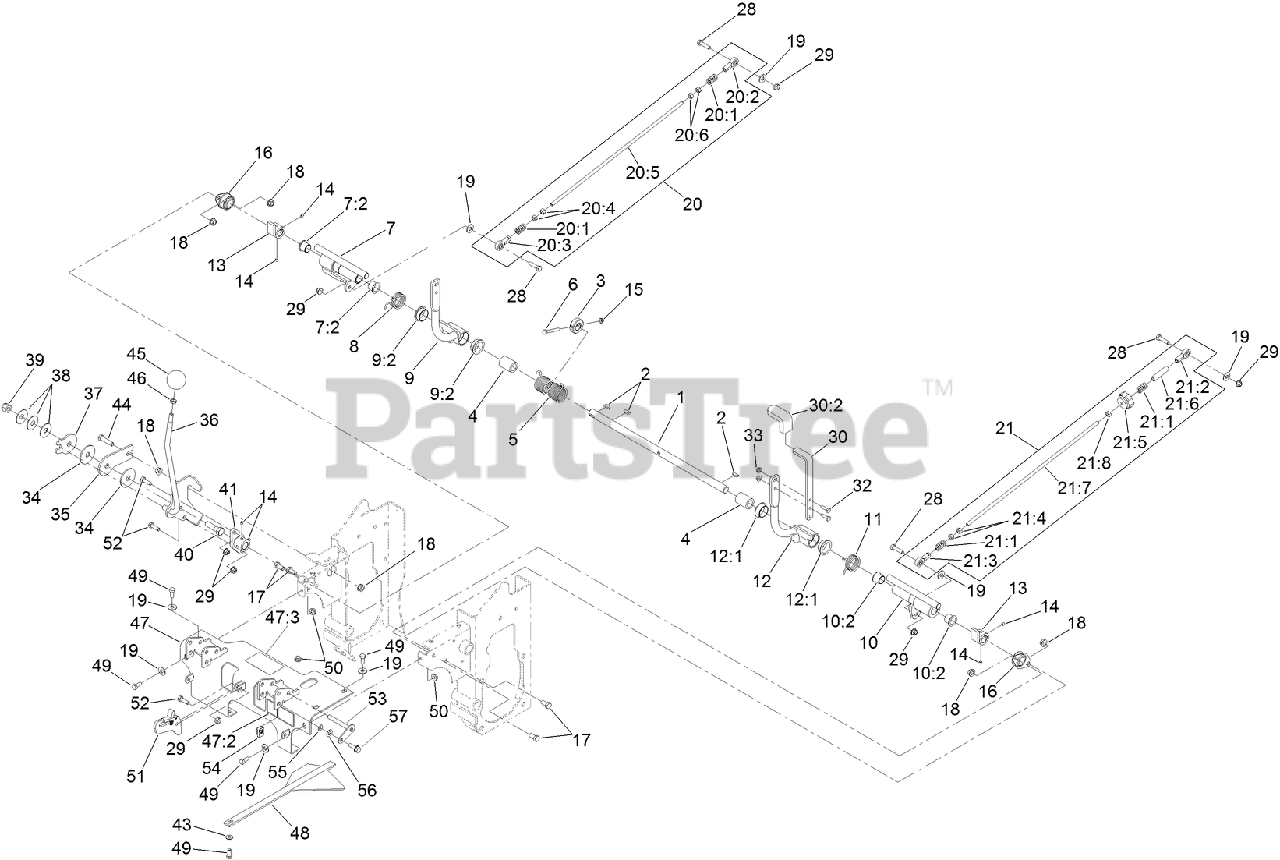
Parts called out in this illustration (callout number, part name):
1	SHAFT-CONTROL, SPEED
2	KEY-WOODRUFF
3	STOP-HUB, CENTER
4	BUSHING-PLASTIC
5	SPRING-TORSION, DOUBLE
6	SCREW-HH
7	RH CONTROL HUB ASM
7:2	BEARING-FLANGE, IGLIDE
8	SPRING-TORSION, RH
9	RH STEERING HANDLE ASM
9:2	BEARING-FLANGE, IGLIDE
10	LH CONTROL HUB ASM
10:2	BEARING-FLANGE, IGLIDE
11	SPRING-TORSION, LH
12	LH STEERING HANDLE ASM
12:1	BEARING-FLANGE, IGLIDE
13	HUB-SPEED CONTROL
14	SCREW-SET
15	NUT-LOCK, NI
16	BEARING-FLANGE, SIDE
17	SCREW-HH
18	NUT-HHF, WHIZ
19	WASHER-FLAT
20	RH PUMP LINKAGE ASM
20:1	SPRING-COMPRESSION
20:2	BALLJOINT-RH
20:3	BALLJOINT-LH
20:5	ROD-LINKAGE, STEERING
20:6	NUT-HEX
21	LH PUMP LINKAGE ASM
21:1	SPRING-COMPRESSION
21:2	BALLJOINT-RH
21:3	BALLJOINT-LH
21:5	KNOB-TRACKING
21:6	SPACER
21:7	ROD-LINKAGE, STEERING
21:8	NUT-HEX
28	SCREW-HH
29	NUT-HF, NI
30	HANDLE ASM
30:2	GRIP-HANDLE, STEERING
32	SCREW-HH
33	NUT-HF
34	DISC-FRICTION
35	PLATE-FRICTION, SPEED CONTROL
36	LEVER-SPEED CONTROL
37	PLATE-FRICTION, SPEED CONTROL
38	WASHER-DISC, SPRING
39	NUT-HEX
40	SCREW-HH
41	HUB-CONTROL, SPEED
43	WASHER-PLAIN
44	SCREW-HH
45	KNOB-BALL, SPEED CONTROL
46	NUT-JAM
47	CONSOLE ASM
47:2	DECAL-DANGER, DRIVELINE
47:3	DECAL-MOTOR, WHEEL
48	GUIDE-PLENUM
49	SCREW-HH
50	NUT-HF
52	SCREW-HH
53	PIN-FLAG
54	NUT-CLIP, U
55	NUT-PUSH
56	WASHER-THRUST
57	SCREW-HHF
